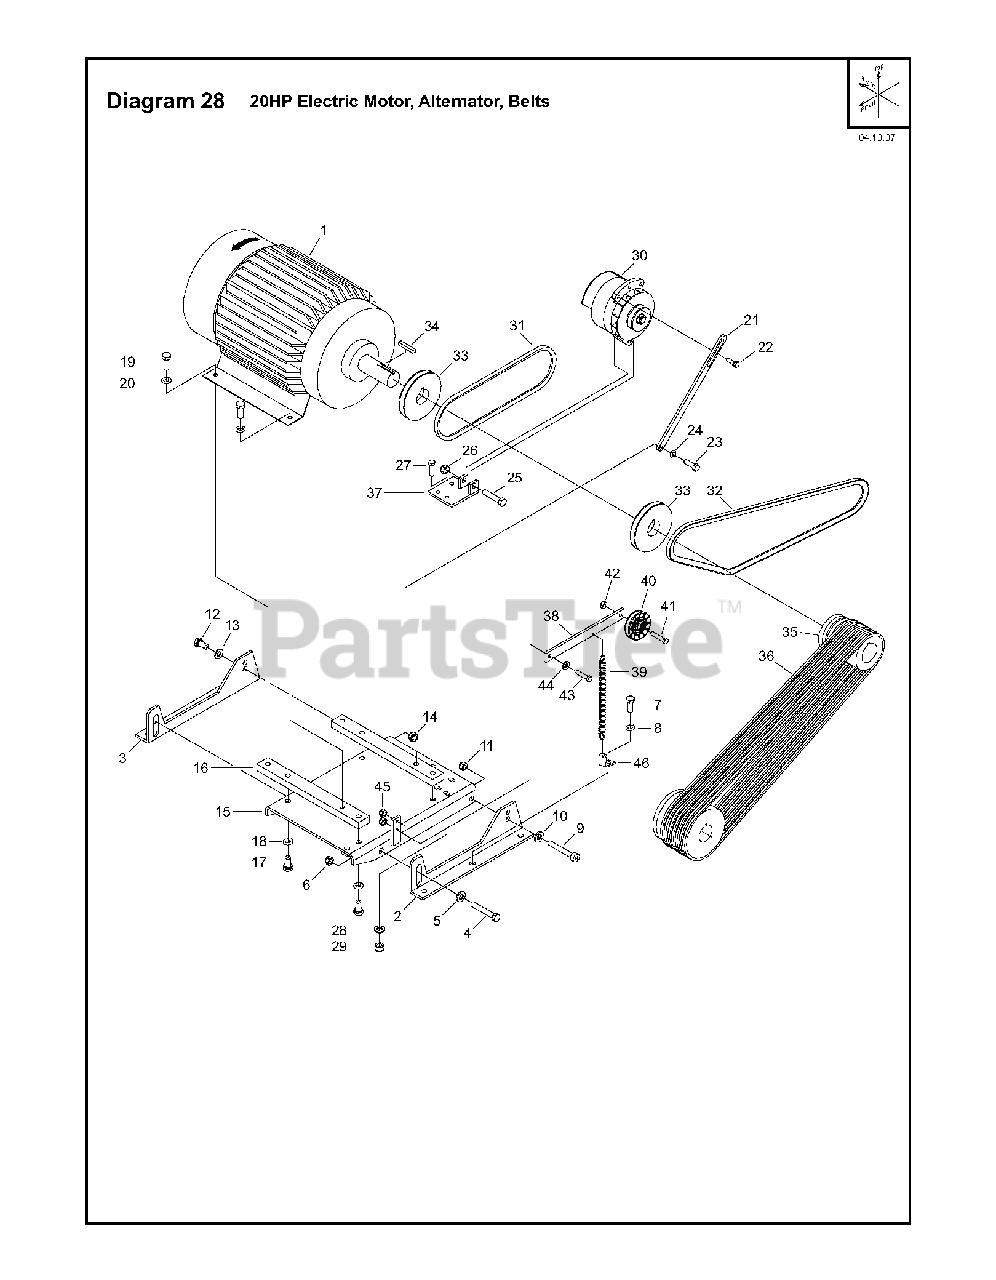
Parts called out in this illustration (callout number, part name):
2	BRACKET. ENGINE BASE LH PTD
3	BRACKET. ENGINE BASE RH. BLACK
5	WASHER
6	LOCKNUT. FIBER M12 DIN 985 Z/P
7	HHCS. M12 x 1.75 x 30 DIN933ZP
8	LOCKWASHER. SPLIT .5 Z/P
9	SHCS. M12 x 1.75 x 40mm
10	WASHER
11	LOCKNUT. FIBER M12 DIN 985 Z/P
12	HHCS. M12 x 1.75 x 30 DIN933ZP
13	WASHER
14	LOCKNUT. FIBER M12 DIN 985 Z/P
15	BASE. MOTOR-20HP EL METRIC BLK
17	HHCS. M12 x 1.75 x 25 DIN933ZP
18	LOCKWASHER. SPLIT .5 Z/P
20	LOCKWASHER. SPLIT .5 Z/P
21	DECAL
22	FLNGBLT. 5/16-18 X 1 GR5 Z/P
23	HHCS. M10 x 1.5 x 25 DIN933 ZP
24	LOCKWASHER. SPLIT M10
25	HHCS. M12 x 1.75 x 65 DIN931ZP
26	LOCKNUT. FIBER M12 DIN 985 Z/P
27	HHCS. M10 x 1.5 x 40 DIN933 ZP
29	LOCKNUT. FIBER M10 DIN 985
30	ALTERNATOR. 12V 37AMP #YB69
34	KEY. BEVEL END .375 X 4
35	PULLEY
36	V-BELT
37	BRACKET. MTG - ALT BLK
38	IDLER LEVER 1/4 X 1 X 10-1/2
42	LOCKNUT. FIBER M10 DIN 985
45	LOCKNUT. FIBER M10 DIN 985
46	DECAL
